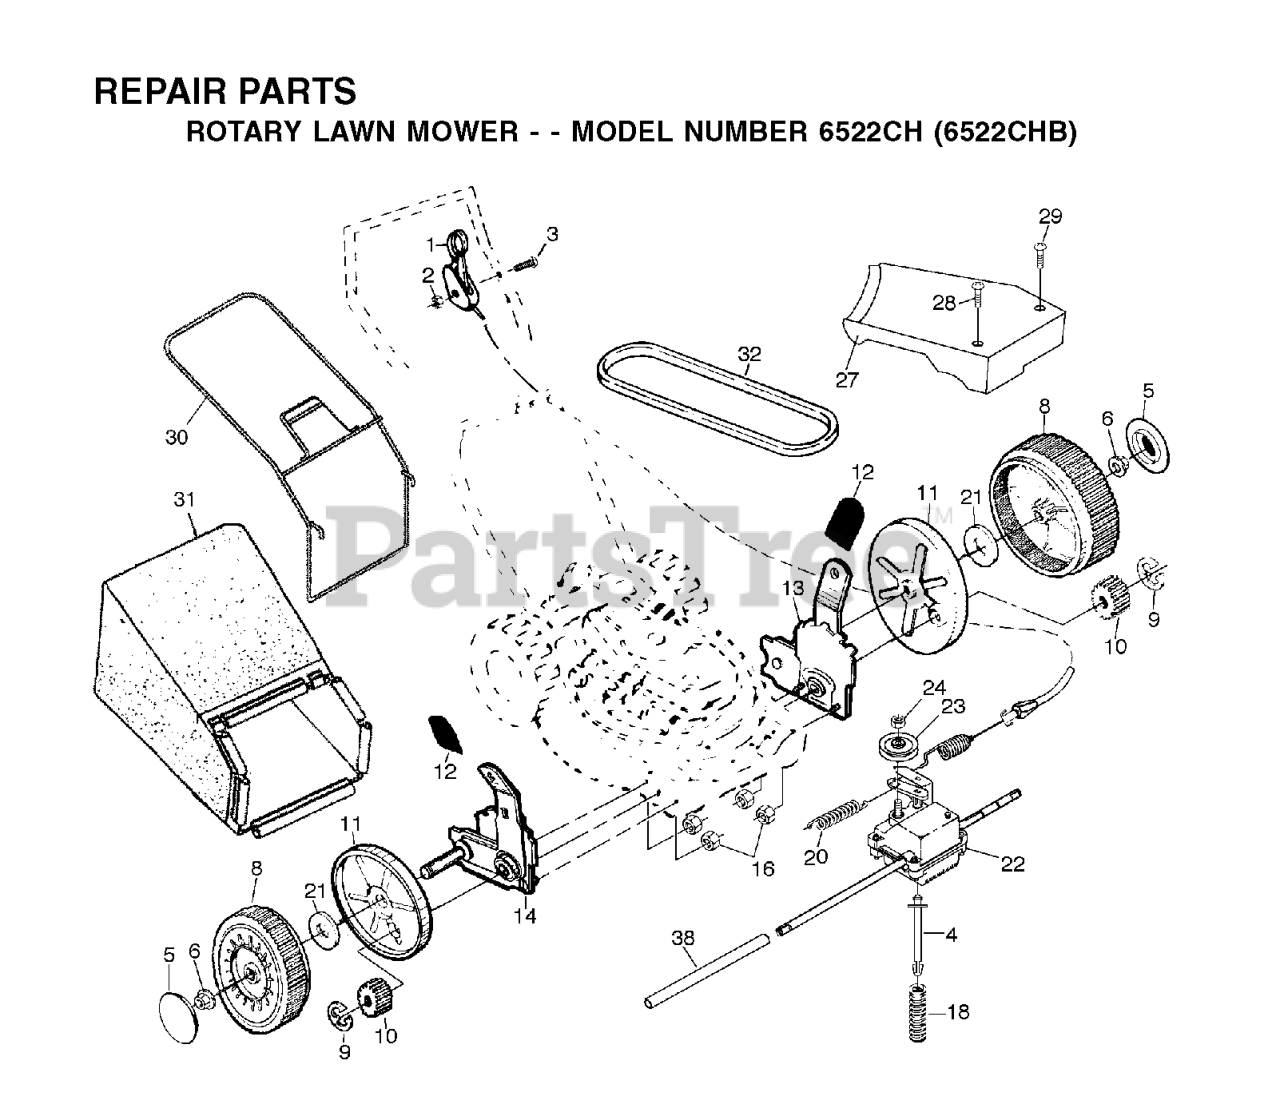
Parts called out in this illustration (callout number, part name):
1	DRIVE CONTROL
2	LOCK NUT
3	SCREW.PAN.HEAD
4	SPRING RETAINER
5	CAP.HUB.BLACK.WALK
6	NUT
8	WHEEL
9	E-RING 7/16 RE
10	PINION GEAR
11	DUST SHROUD PM
13	WHEEL ADJ ASM (L)
14	KIT.ADJUSTER.ASM.(151514).RT
16	NUT
18	SPRING.EXTENSION
21	WASHER FLUT
22	GEAR CASE ASMBLY
23	PULLEY
24	FLANGED LOCKNUT 3/8-16 ZINC
27	DRIVE COVER-GRAY
29	SCREW.SLOT.TORX.
30	CATCHER FRAME
31	Grass Bag
32	BELT THERM .32
38	DRV SHAFT TUBE PM
